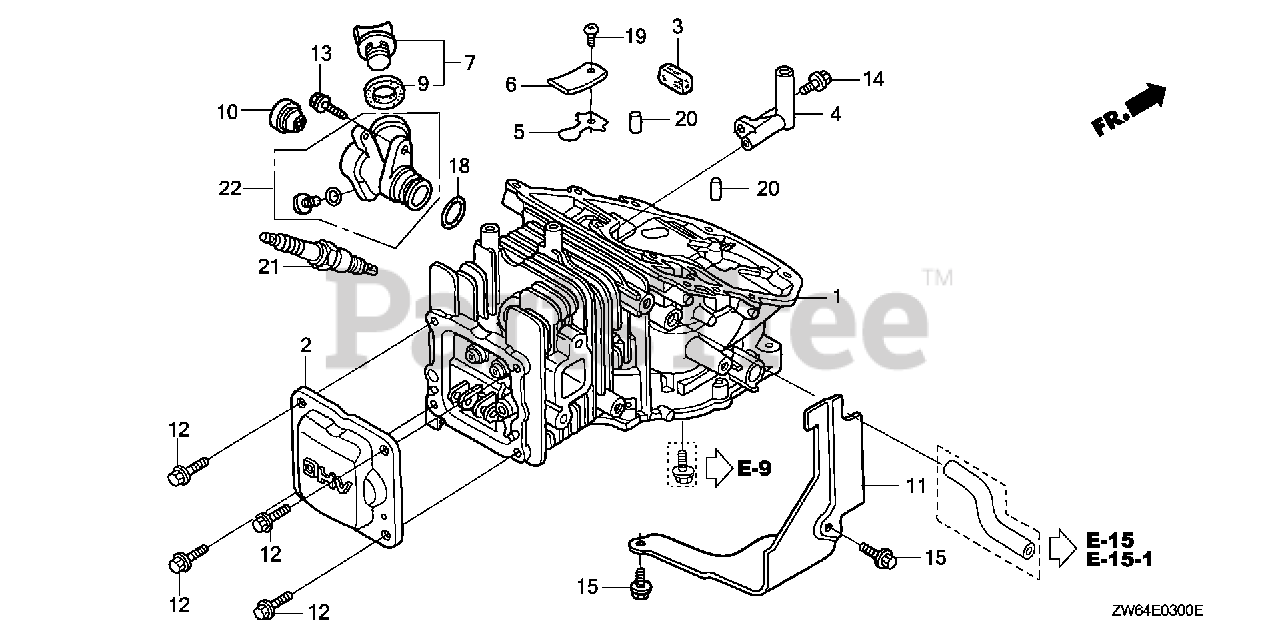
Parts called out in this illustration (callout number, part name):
1	CYLINDER
2	COVER, HEAD *NH105* (MAT BLACK)
3	FILTER, BREATHER
4	PIPE, BREATHER
5	VALVE, OIL OUTLET
6	PLATE, STOPPER
7	CAP ASSY., OIL FILLER
8	EXTENSION KIT, OIL LEVEL FINDER
9	GASKET, OIL FILLER CAP
10	FINDER, OIL LEVEL
11	SHROUD
12	BOLT, FLANGE (5X12) (CT200)
13	BOLT, FLANGE (5X16)
14	BOLT (4X10)
15	BOLT, FLANGE (5X10) (CT200)
16	BOLT, OIL CHECK
16	BOLT, OIL CHECK (8X8)
17	GASKET (8MM)
18	O-RING (22.1X2.2)
19	SCREW, PAN (3X5)
20	ROLLER (6X15)
21	SPARK PLUG (U14FSR-UB)
21	SPARK PLUG (CR4HSB)
22	EXTENSION KIT, OIL LEVEL FINDER
